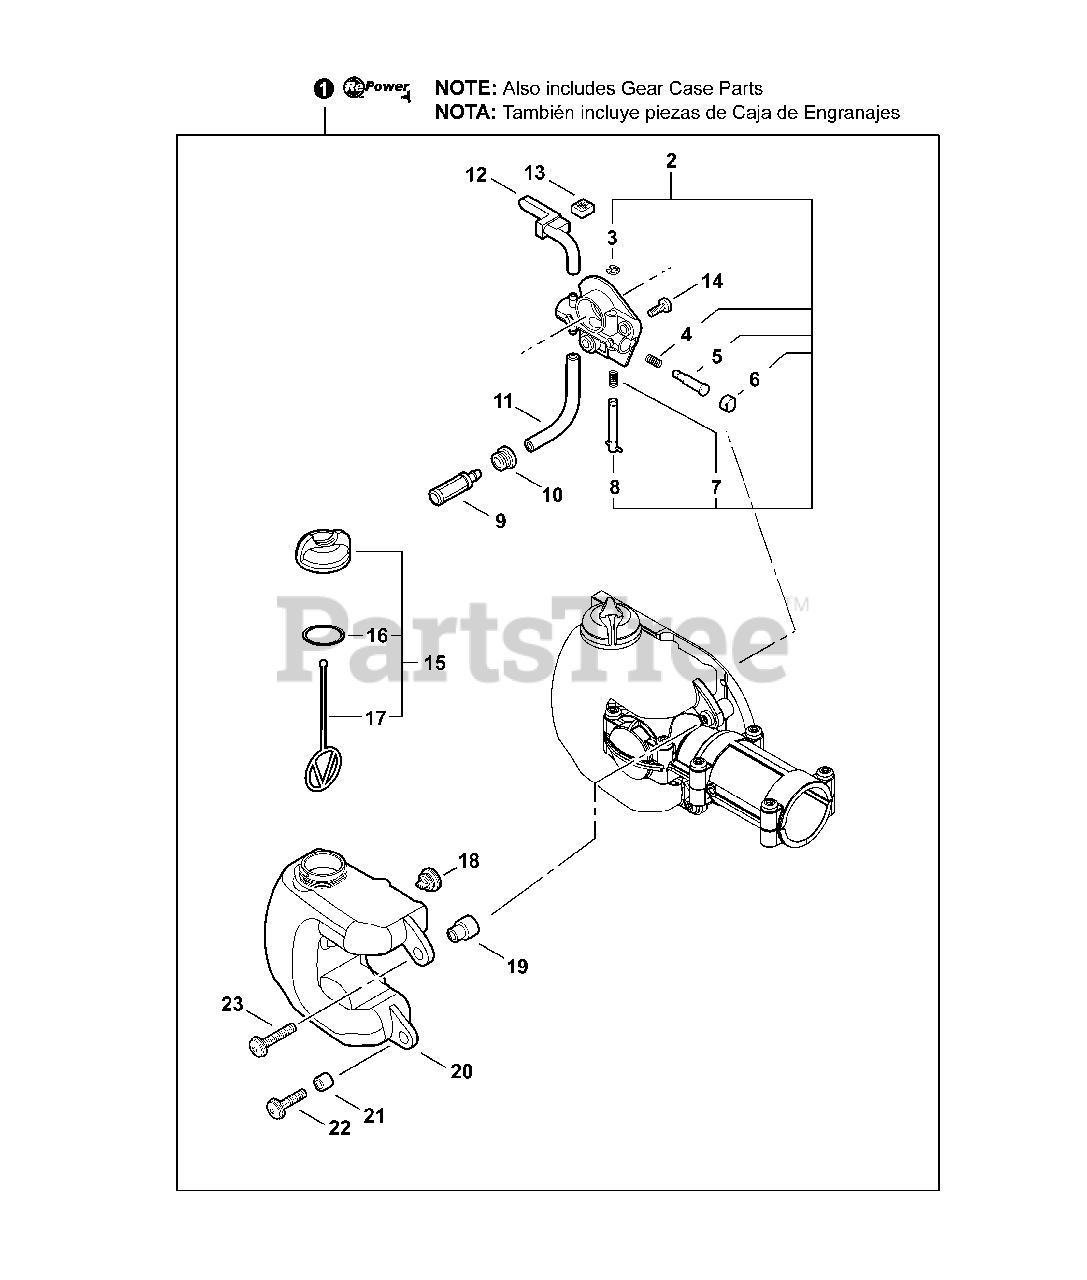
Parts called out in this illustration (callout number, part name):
1	CUTTING HEAD ASY
2	AUTO-OILER ASY
3	RING, RETAINING
5	PLUNGER
6	CAP, OIL PUMP
8	NEEDLE, ADJUST
9	FILTER, OIL
10	GROMMET
11	PIPE - 3×6×75 -- BLACK
12	PIPE, OIL OUTLET
13	PAD, FOAM
14	SCREW - 5×10
15	CAP ASY - ORANGE
16	O-RING - 18
17	CONNECTOR, CAP
18	VENT ASY
19	COLLAR 6
20	TANK, OIL
22	SCREW - 5×20
23	SCREW - 5×25
